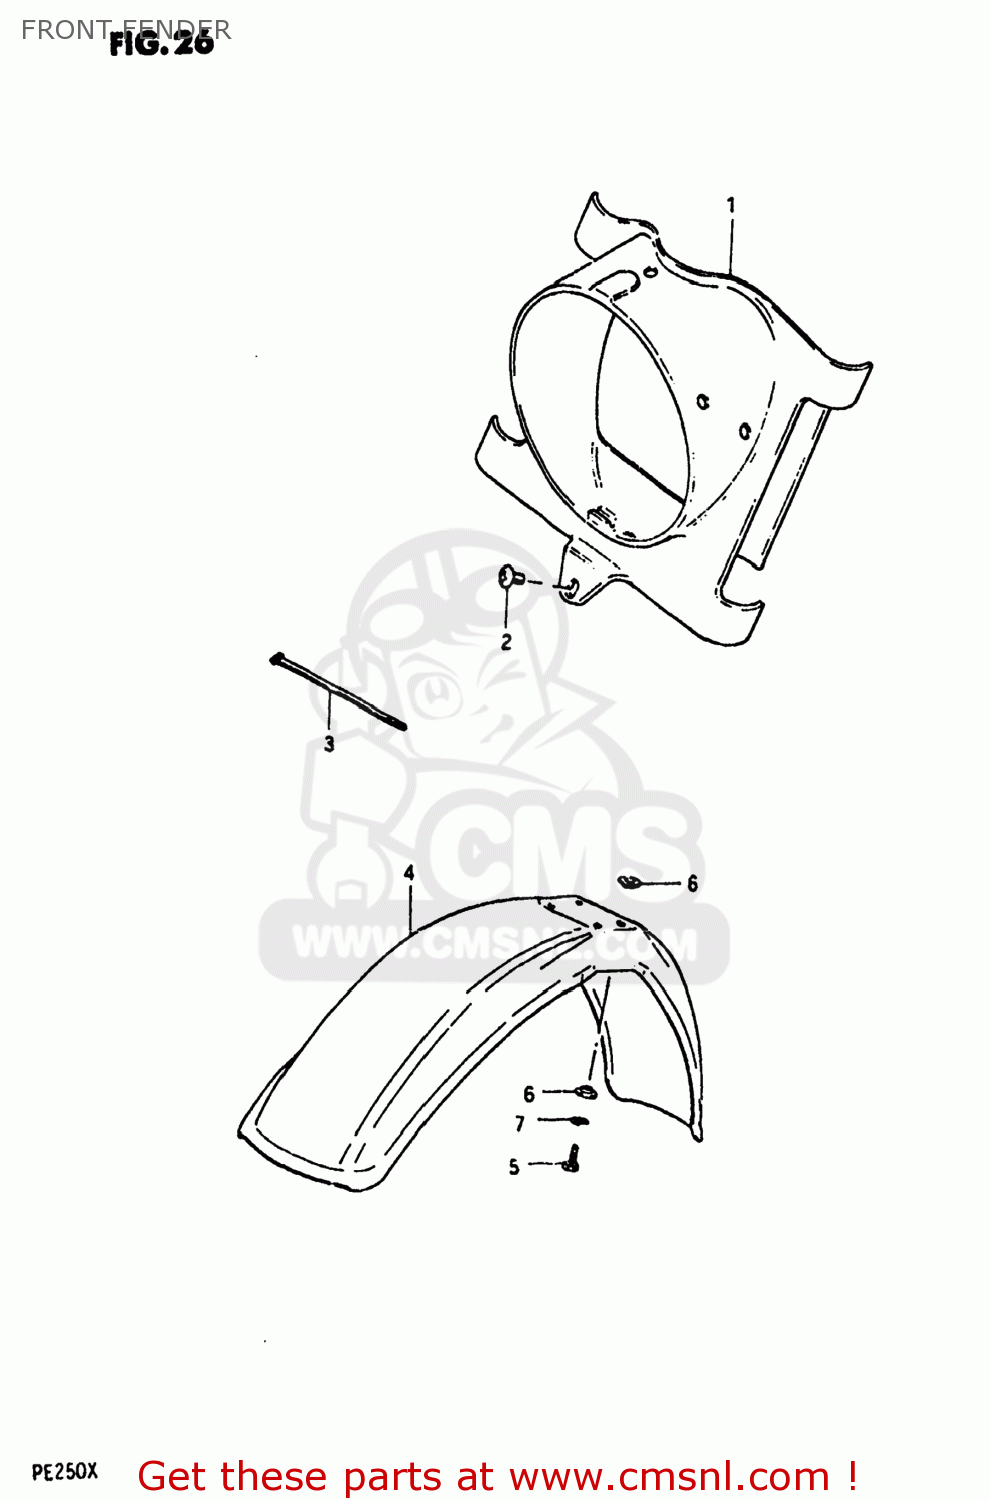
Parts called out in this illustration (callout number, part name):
1	HOUSING,HEADLAMP
2	SCREW
3	CLAMP
4	FENDER,FRONT
5	BOLT, UPPER
6	WASHER
7	LOCK WASHER
